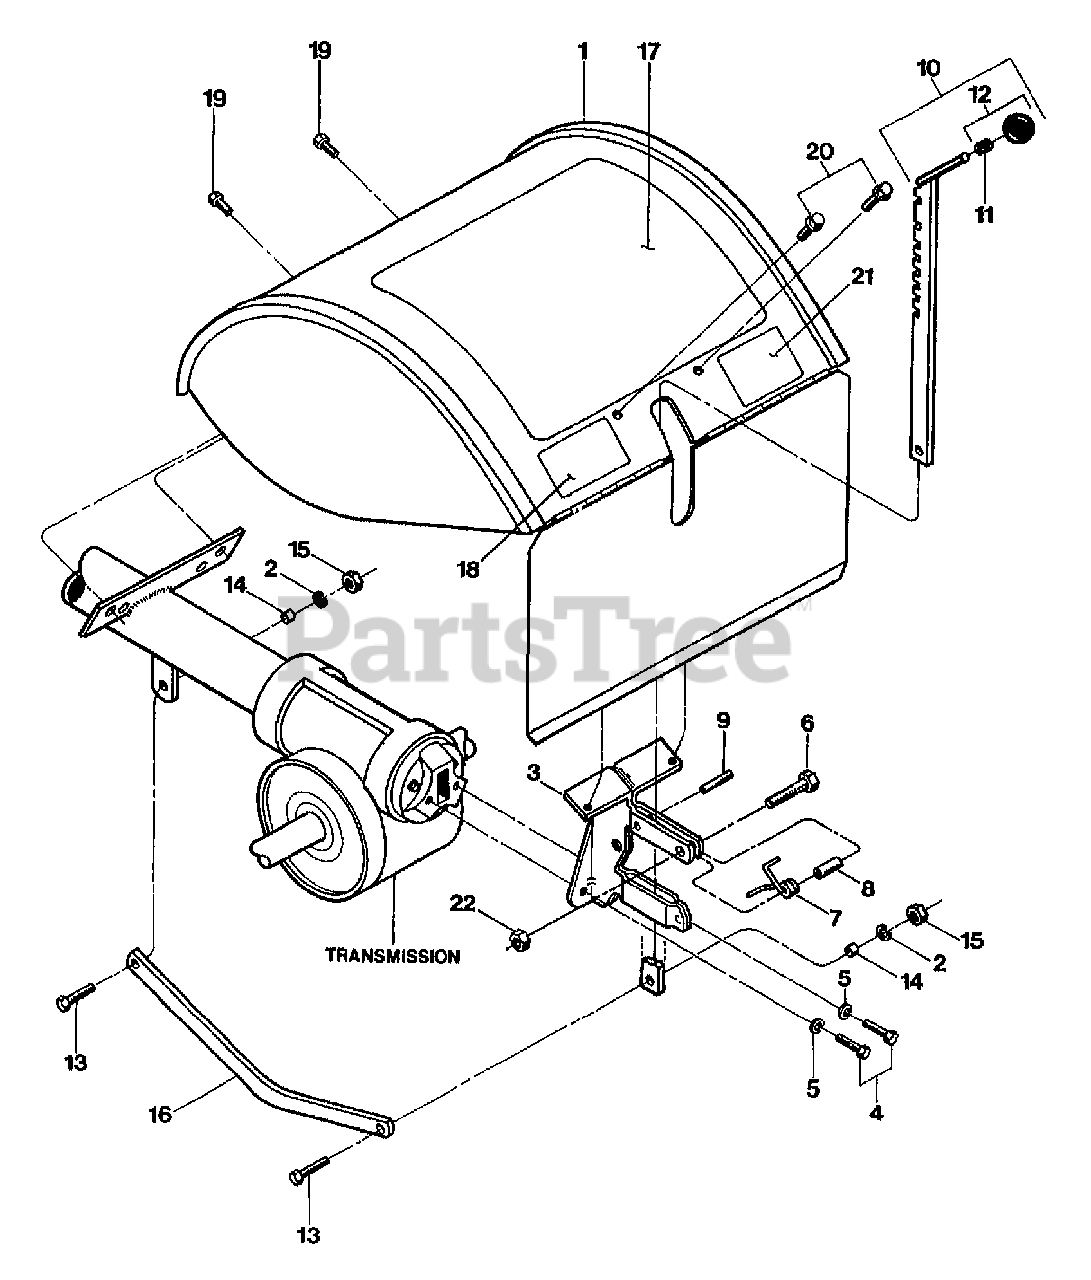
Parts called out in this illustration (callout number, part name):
1	HOOD W/DECAL ECONO OPC (INCL. DECALS #20816, 2608, AND 20814)
2	WASHER-LK .375 @ DEPL
3	BRKT W/ROLL PIN (9308)
4	SCR-HHC 5/16-18X.75 GR 5 ZP (BRACKET TO BEARING CAP)
5	WASHER-LK .312 ZP
6	SCR-HH 1/4-20X1.0
7	SPRING-TORSION
8	SPACER-.250X.343X.375
9	PIN-ROLL .25 X 1 (SPIRAL)
10	DEPTH REGULATOR W/KNOB (INCL. 11 & 12)
11	RING-TOLERANCE .5325 ID
12	KNOB-CONTROL (INCL. 11)
13	SCR-HH 3/8-16X1.25
14	BUSHING-.5X.375X.3
15	NUT-HEX 3/8-16 ZP
16	DRAG BAR-BENT
17	DECAL-HOOD OPER INST OPC
18	DECAL-LOGO (MODEL NAME DECAL)
19	SCR-HWH 5/16-18 X .5 STH
20	SCR-HWH 1/4-20 X .5 STH (ATTACHES HOOD TO DEPTH REGULATOR BRACKET)
21	DECAL-TINE WARN SM FRAME
22	NUT-LK 1/4-20
